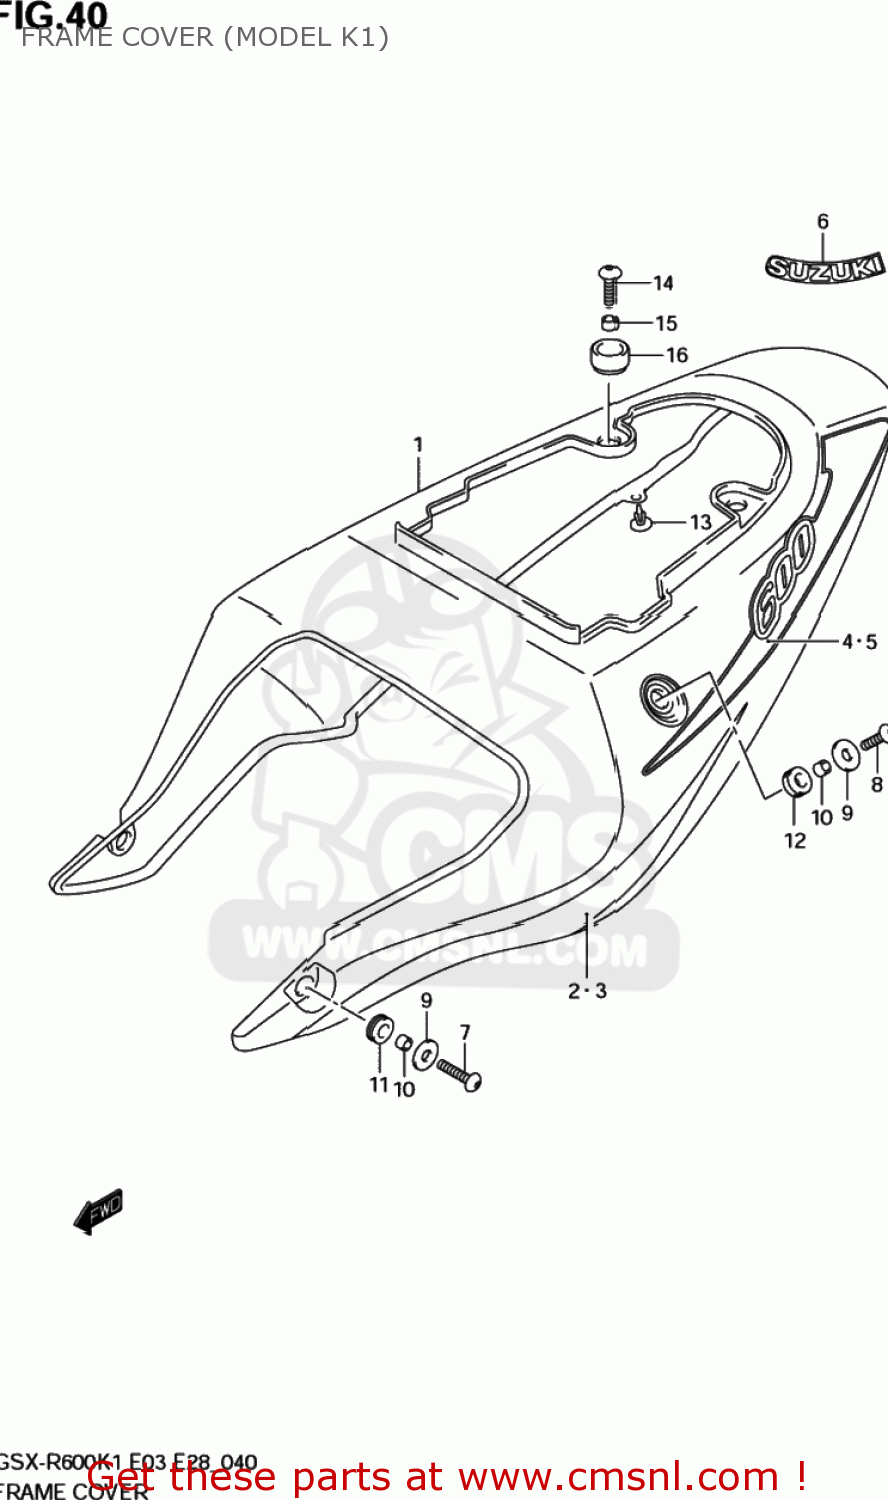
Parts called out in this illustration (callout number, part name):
1	COVER, FRAME (YELLOW)
2	TAPE,FRAME COVER,R
3	TAPE,FRAME COVER,L
4	TAPE,RR,R
5	TAPE,RR,L
6	EMBLEM,SUZUKI
7	SCREW(6X30)
8	SCREW(6X25)
9	WASHER(6.5X20X2)
10	SPACER(6.5X10X7)
11	CUSHION,FRAME COVER FR
12	CUSHION,FRAME COVER SIDE
13	CLIP(BLACK)
14	SCREW(6X25)
15	SPACER(6.5X10X9.4)
16	CUSHION
